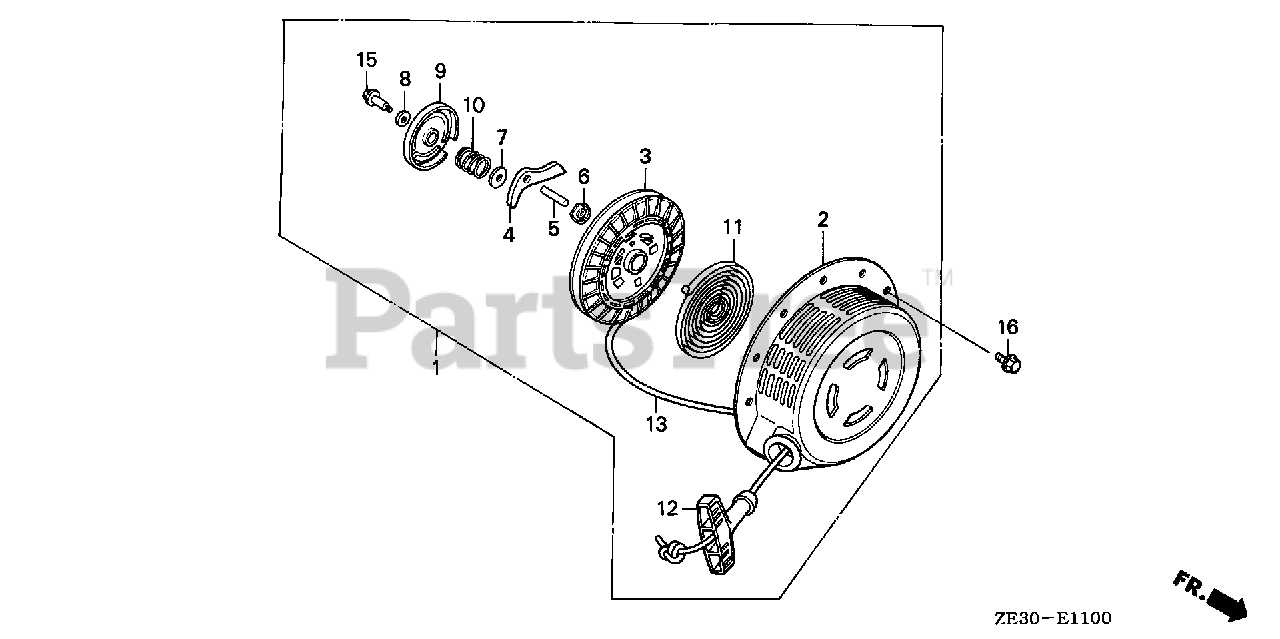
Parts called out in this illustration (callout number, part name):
1	STARTER ASSY., RECOIL *R8* (BRIGHT RED)
2	CASE, RECOIL STARTER *R8* (BRIGHT RED) (NOT AVAILABLE)
3	REEL, STARTER
4	RATCHET, STARTER
5	SHAFT, RATCHET (NOT AVAILABLE)
6	PLATE, GUIDE
7	PLATE A, FRICTION
8	PLATE B, FRICTION
9	COVER, STARTER REEL (NOT AVAILABLE)
9	COVER, STARTER REEL
10	SPRING, FRICTION (D=18.5MM / L=20.5MM)
10	SPRING, FRICTION (D=13.0MM / L=16.3MM)
11	SPRING, RETURN
12	GRIP, STARTER
13	ROPE, STARTER (N/A: USE ALT P/N 08560-ZG921-11)
15	BOLT, REEL COVER
16	BOLT, FLANGE (6X8)
